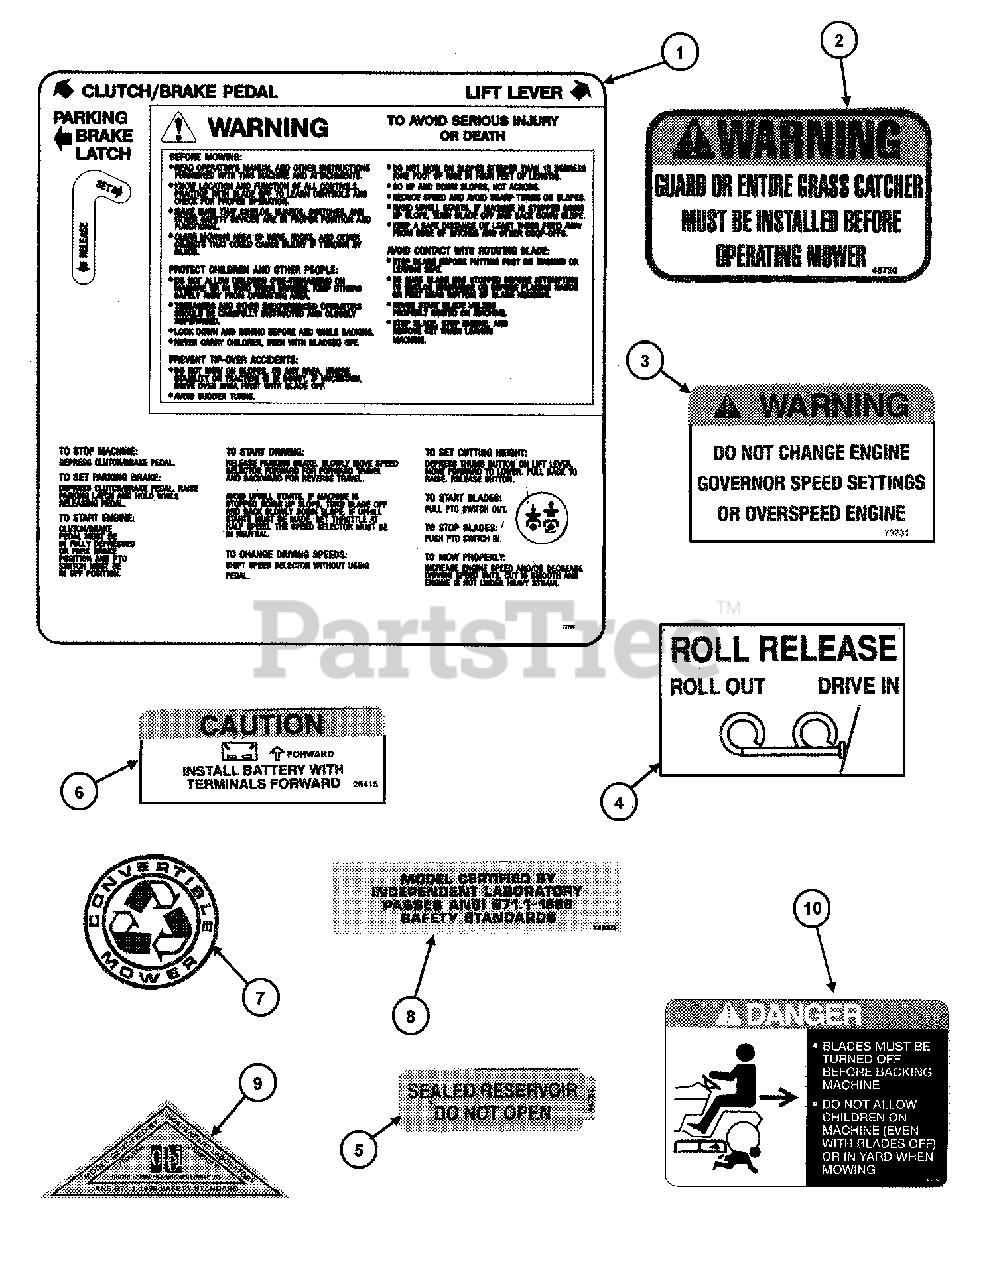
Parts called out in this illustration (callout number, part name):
1	DECAL, Instructions Frame Top Electric Clutch
2	DECAL, Chute/Deflector
3	DECAL, Warning-Speed Setting 14, 16, & 18 HP ENGINES
4	DECAL, Roll Release
5	DECAL, Hydro Reservoir
6	DECAL, Caution-Battery Installation Fender
7	DECAL, Medallion
8	DECAL, Certification, B71.1-1998
9	DECAL, OPEI Ride-On
10	DECAL, No Mow in Reverse
